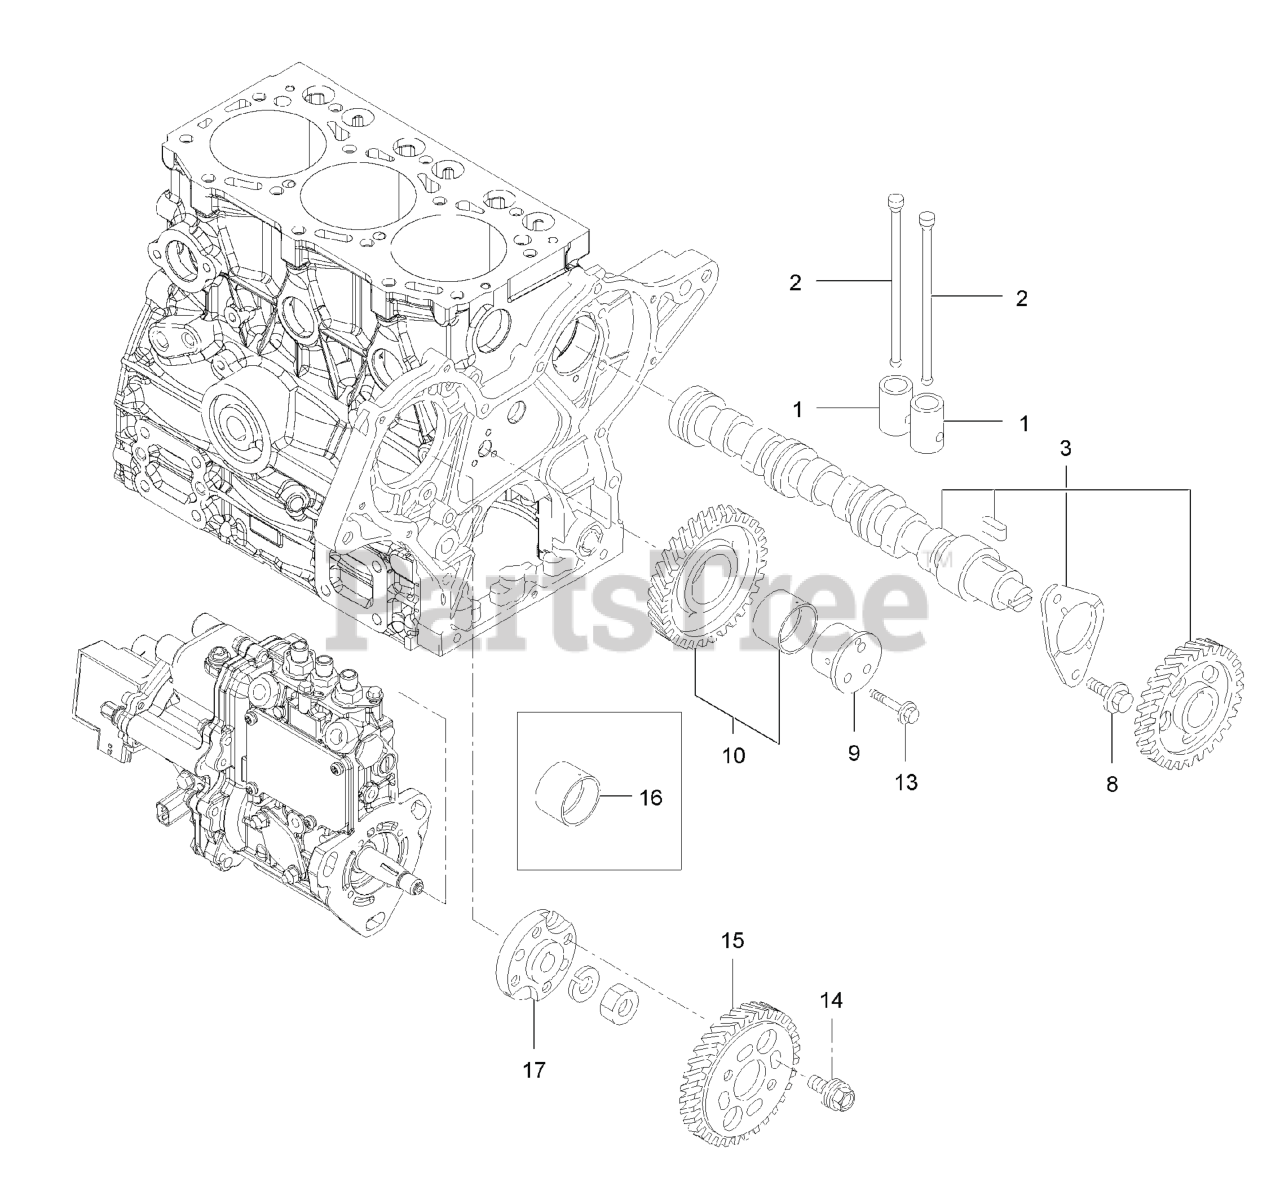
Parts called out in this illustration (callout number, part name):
2	PUSH-ROD
3	CAMSHAFT ASM
9	SHAFT-IDLE
10	GEAR ASSY-IDLE
15	GEAR-PUMP
16	BUSH-IDLE GEAR
